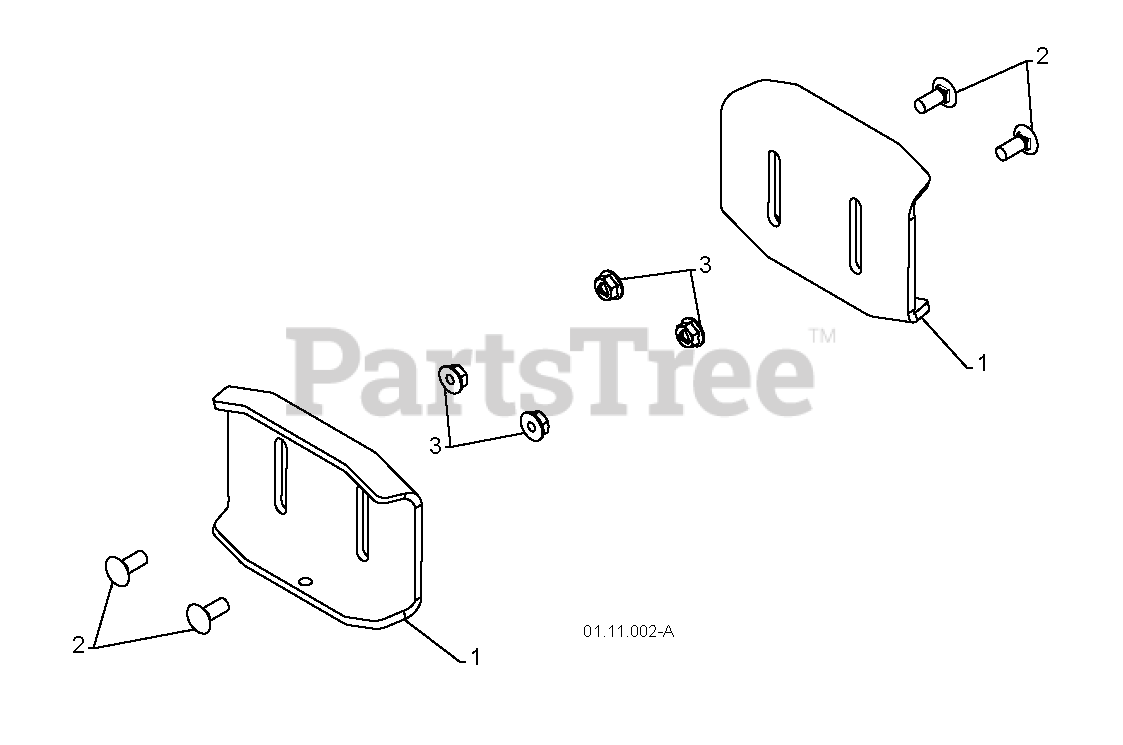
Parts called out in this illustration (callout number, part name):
1	SKID PLATE
2	BOLT
3	NUT.LOCK.5/16-18
